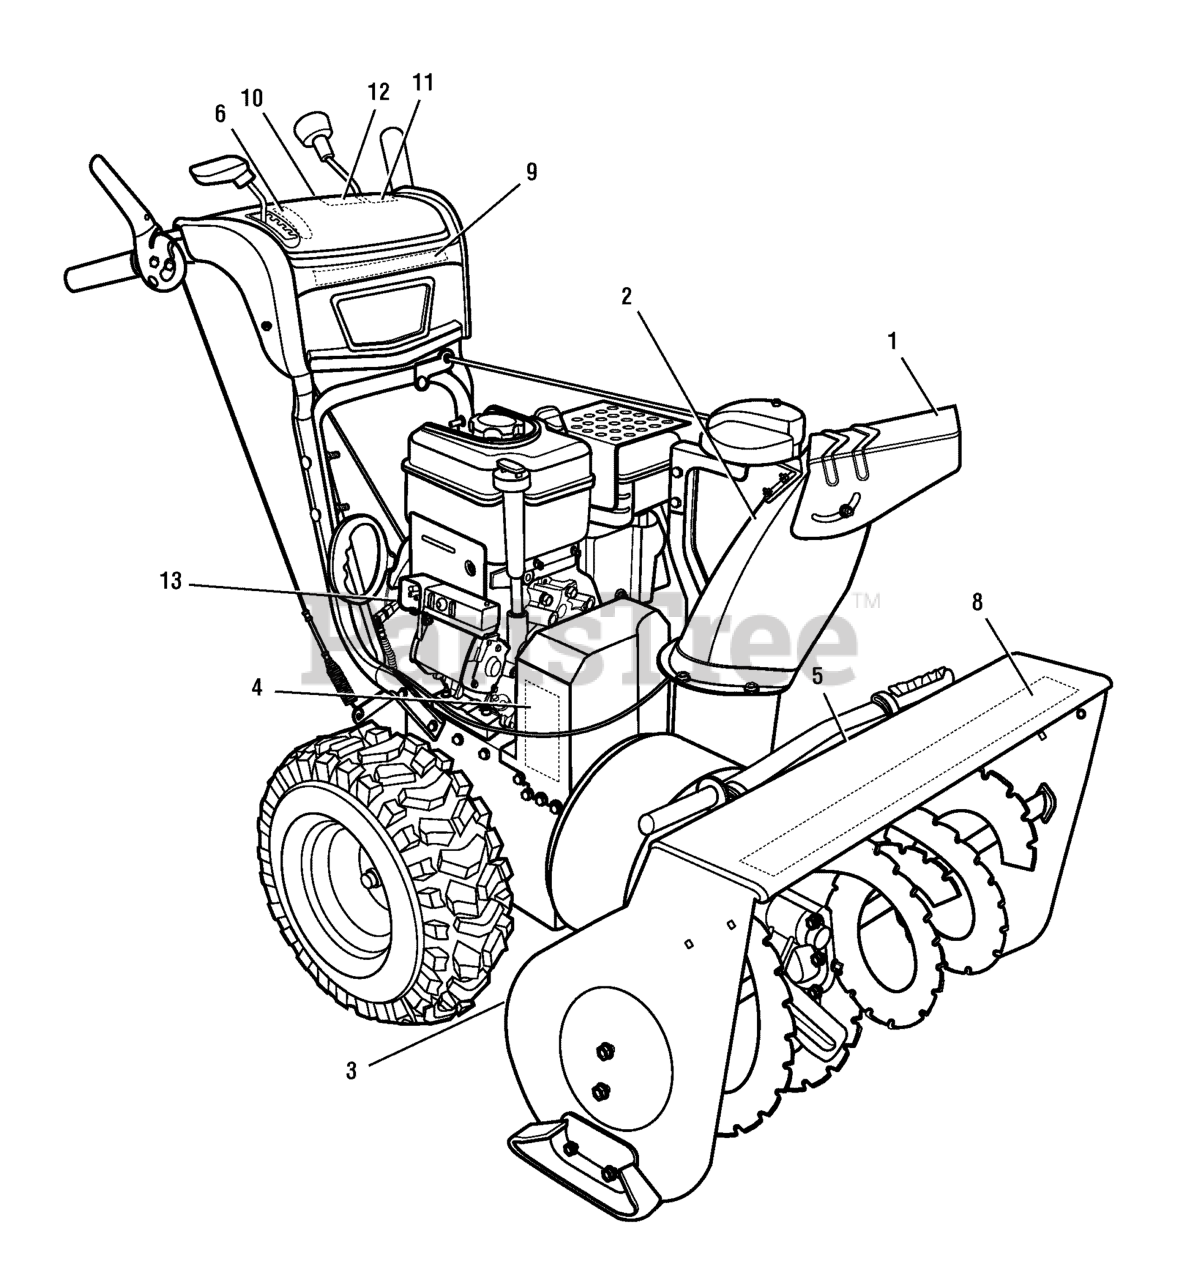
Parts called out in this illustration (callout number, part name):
1	DECAL, THROWN OBJECTS
2	DECAL, DANGER CHUTE
3	DECAL, ISO AUGER FR/EN
4	DECAL, BELT STRETCH
5	DECAL, CLEAN & CLEAR BRUSH
6	DECAL, SHIFT
8	DECAL, MURRAY AUGER HOUSING
9	DECAL, MURRAY DASH
10	DECAL, LUBRICATION
11	DECAL, MAIN DASH
12	DECAL, DANGER WARNING
13	DECAL, Over Adjustment of Friction Disc
